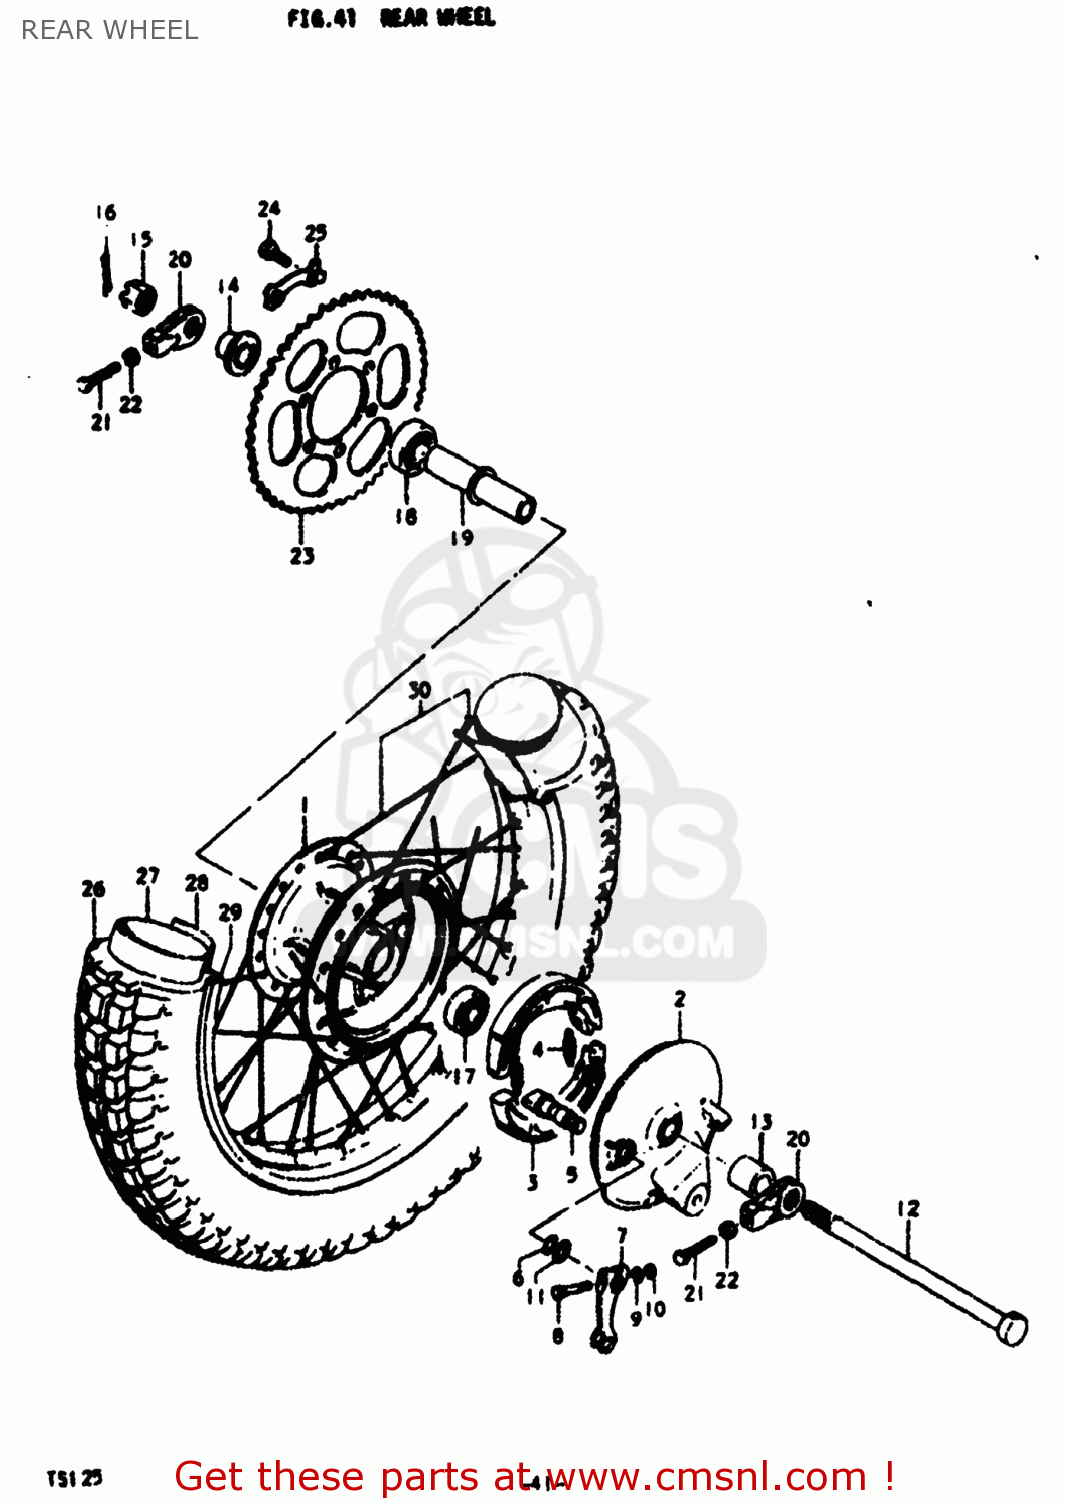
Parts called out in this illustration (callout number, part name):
1	HUB,REAR WHEEL
2	PANEL,RR BRAKE ANCHOR
3	SHOE,BRAKE
4	SPRING(L:34)
5	CAM,FRONT BRAKE
6	O-RING (D:2.4 ID:13.8)
7	LEVER,RR BRAKE CAM
8	BOLT(6X33)
9	WASHER
10	NUT
11	WASHER (14.5X22X1.6)
12	AXLE,REAR
13	SPACER(15.2X22X26)
14	SPACER,RR AXLE,L
15	NUT
16	COTTER PIN
17	BEARING
18	BEARING
19	SPACER,RR WHEEL HUB BEARING
20	ADJUSTER,CHAIN,R
21	BOLT
22	NUT
23	SPROCKET,REAR
24	BOLT(8X30)
25	WASHER
26	TIRE
27	TUBE ASSEMBLY,WHEEL,INNER
28	PROTECTOR,INNER TUBE
29	RIM,REAR WHEEL
30	SPOKE SET,REAR
